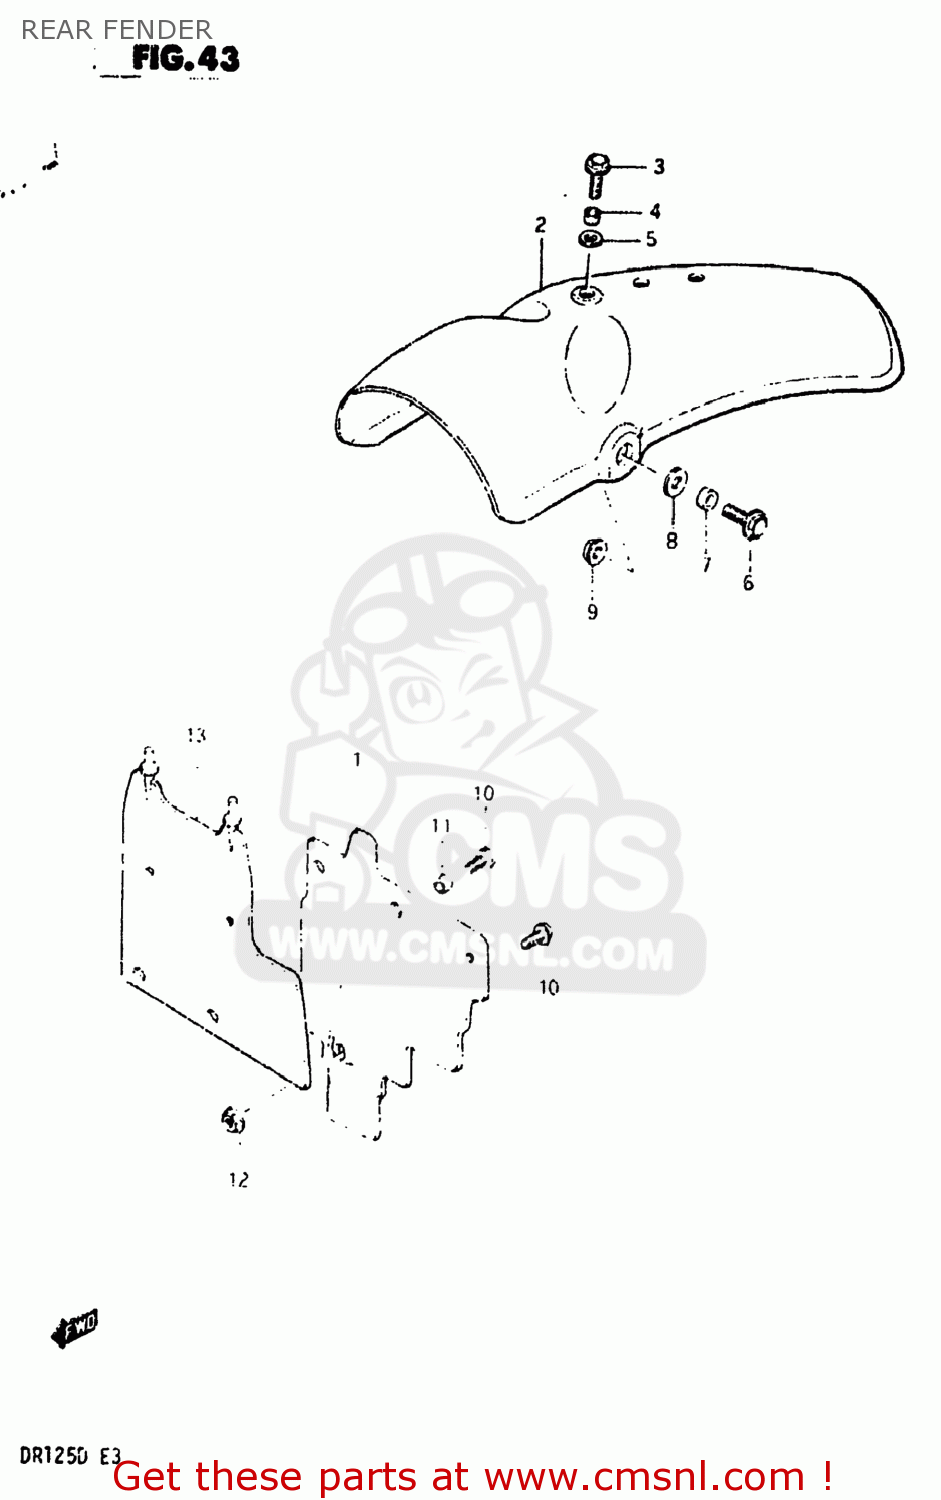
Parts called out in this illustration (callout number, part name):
1	FENDER,REAR
2	FENDER,REAR
3	BOLT
4	SPACER
5	WASHER
6	BOLT
7	SPACER(8.2X14X4.5)
8	WASHER (8.7X22X2)
9	NUT
10	SCREW, FRONT
11	SPACER
12	NUT
13	MUD GUARD,REAR FENDER
